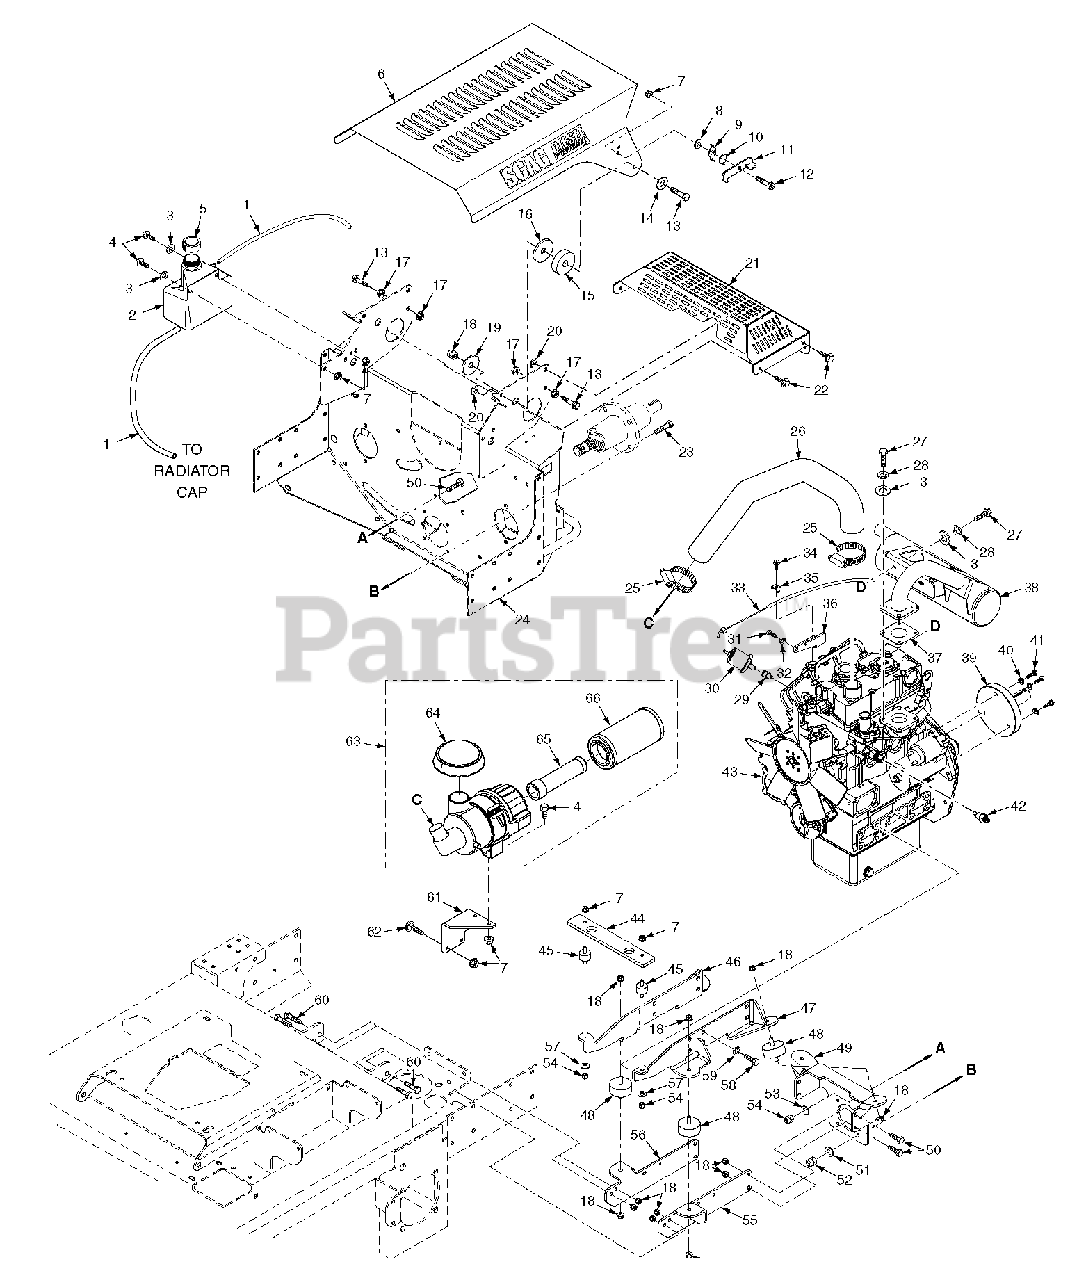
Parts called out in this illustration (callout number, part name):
1	Hose, Coolant Reservoir Bottle
2	Overflow Tank Assy.
3	Flatwasher, SAE 5/16-.344 x .688 x .065
4	Bolt, Hex Head Serr. Flng 5/16-18 x 3/4"
5	Cap, Overflow Tank
6	Hood Assembly w/Decals
7	Nut, Serrated Flange 5/16-18
8	Flatwasher, 3/8-.406 x .812 x .065
9	Lock, Hood Latch
10	Spring, Hood Latch
11	Latch, Hood
12	Bolt, Shoulder 5/16-18 x 1/2"
13	Bolt, Hex Head 3/8-16 x 1-3/4"
14	Flatwasher, 3/8-.391 x .938 x .105
15	Spacer, Hood
16	Disc, Anti Friction
17	Nut, Serrated Flange 3/8-16
18	Nut, Elastic Stop 3/8-16
19	Flatwasher, 3/8-.406 x 1.50 x 7 Gauge
20	U-Nut, 1/4"-20
21	Muffler Guard
22	Bolt, Hex Head Serrated Flange, 1/4-20 x 3/4"
23	Bolt, Hex Head 5/16-18 x 1-3/4" Grd 8
24	Pump Mounting Plate Weldment
25	Clamp, 2-1/4" Max. Dia.
26	Hose, Air Intake
27	Bolt, Hex Head M8-1.25 x 20
28	Lockwasher, 5/16" Spring
29	Elbow, 45 Degree
30	Oil Pressure Sender
31	Bolt, Hex Head M6-1.0 x 16
32	Lockwasher, 1/4" Spring
33	Throttle Cable
34	Screw, Self Tapping
35	Clamp
36	Mounting Bracket, Throttle Cable
37	Gasket, Muffler
38	Muffler, Cat Diesel
39	Stub Shaft, (Cat)
40	Lockwasher, 7/16" Spring
41	Bolt, Hex Head M10 x 1.5 x 35
42	Temperature Sensor, Engine Coolant
43	Engine, Cat Diesel 28HP (Available only through Cat Dealers)
44	Mount, Radiator
45	Mount, Radiator Isolation
46	Mounting Bracket Weldment RH
47	Mounting Bracket Weldment LH
48	Mount, Engine Isolation
49	Plate, Rear Engine Mount
50	Bolt, Hex Head 3/8-16 x 1"
51	Flatwasher, 5/16" (.375 x .875 x .083)
52	Nut, Elastic Stop 5/16-18 Grade 8
53	Lockwasher, 3/8" Spring
54	Nut, Elastic Stop 3/8-16
55	Plate, Engine Mount LH
56	Plate, Engine Mount RH
57	Flatwasher, 3/8" (.406 x 1.50 x 7 ga)
58	Bolt, Hex Head M12-1.25 X 25mm
59	Lockwasher, 1/2" Spring
60	Bolt, Hex Head 3/8-16 x 1"
61	Bracket, Air Cleaner Mount
62	Bolt, Carriage 5/16-18 x 3/4"
63	Air Filter Assembly (Enginaire p/n 68665)
64	Rain Cap (Enginaire p/n 68381)
65	Air Filter, Inner (Enginaire p/n 68300)
66	Air Filter, Outer (Enginaire p/n 68340)
